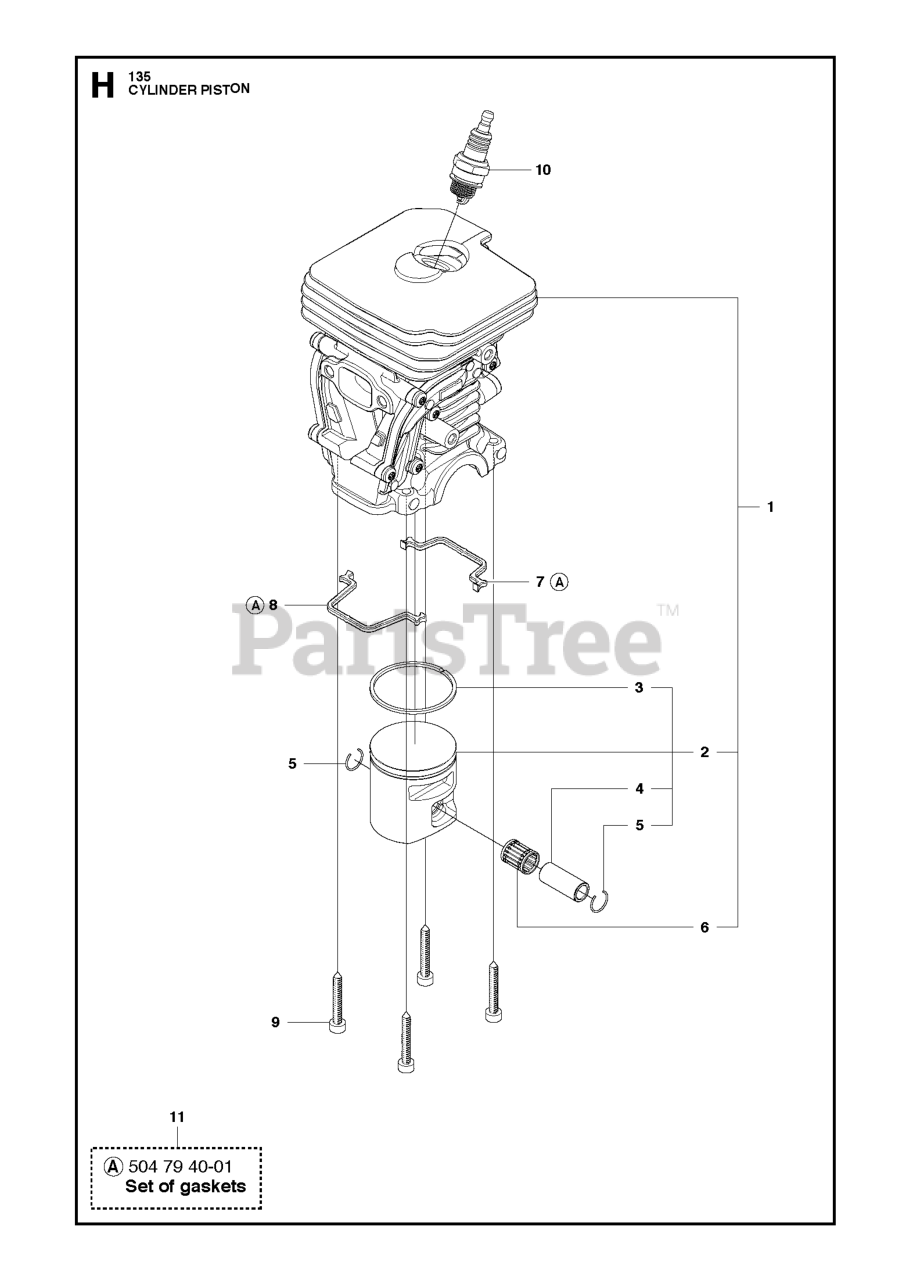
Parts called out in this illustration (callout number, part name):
1	ASSY, CYLINDER 435 AND 435E
2	PISTON ASSY
3	PISTON RING
4	PISTON PIN
5	LOCKING RING
6	SUPPORT BUSHING
7	GASKET
8	GASKET
9	SCREW MC6S 5X25
10	SPARK PLUG M14X1.25 NGK BPMR7A
11	GASKET SET
